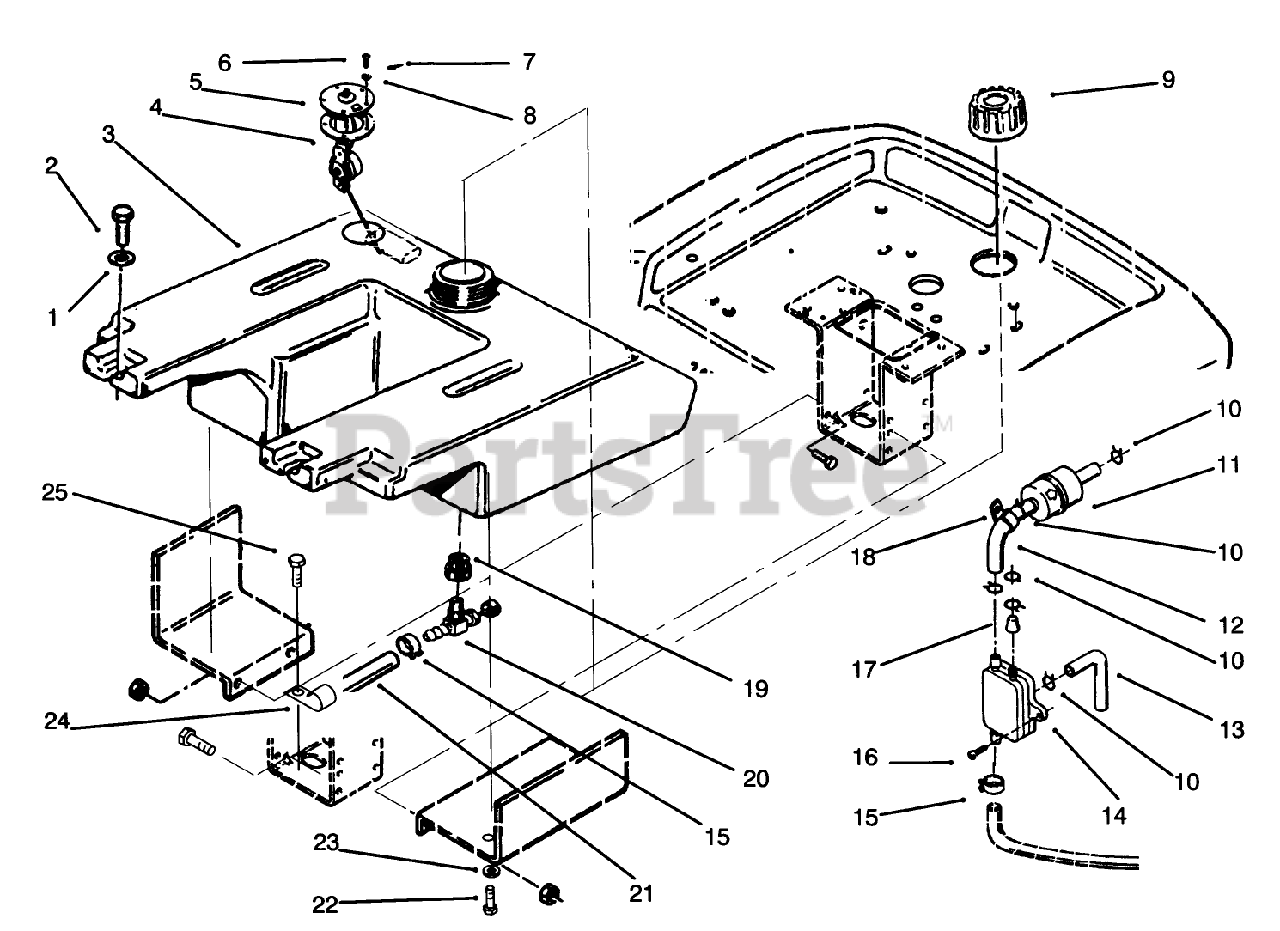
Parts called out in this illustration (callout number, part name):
1	WASHER-FLAT
4	GASKET-SENDER, FUEL
7	TERMINAL-GROUND
8	WASHER-LOCK
9	GAS CAP ASM
10	CLAMP-HOSE
16	SCREW-TAPPING PAN HD
18	CLAMP
20	VALVE-FUEL
21	FUEL HOSE 75" OF 6554
22	SCREW-HH
23	WASHER-LOCK
25	SCREW-HH, LOCK
